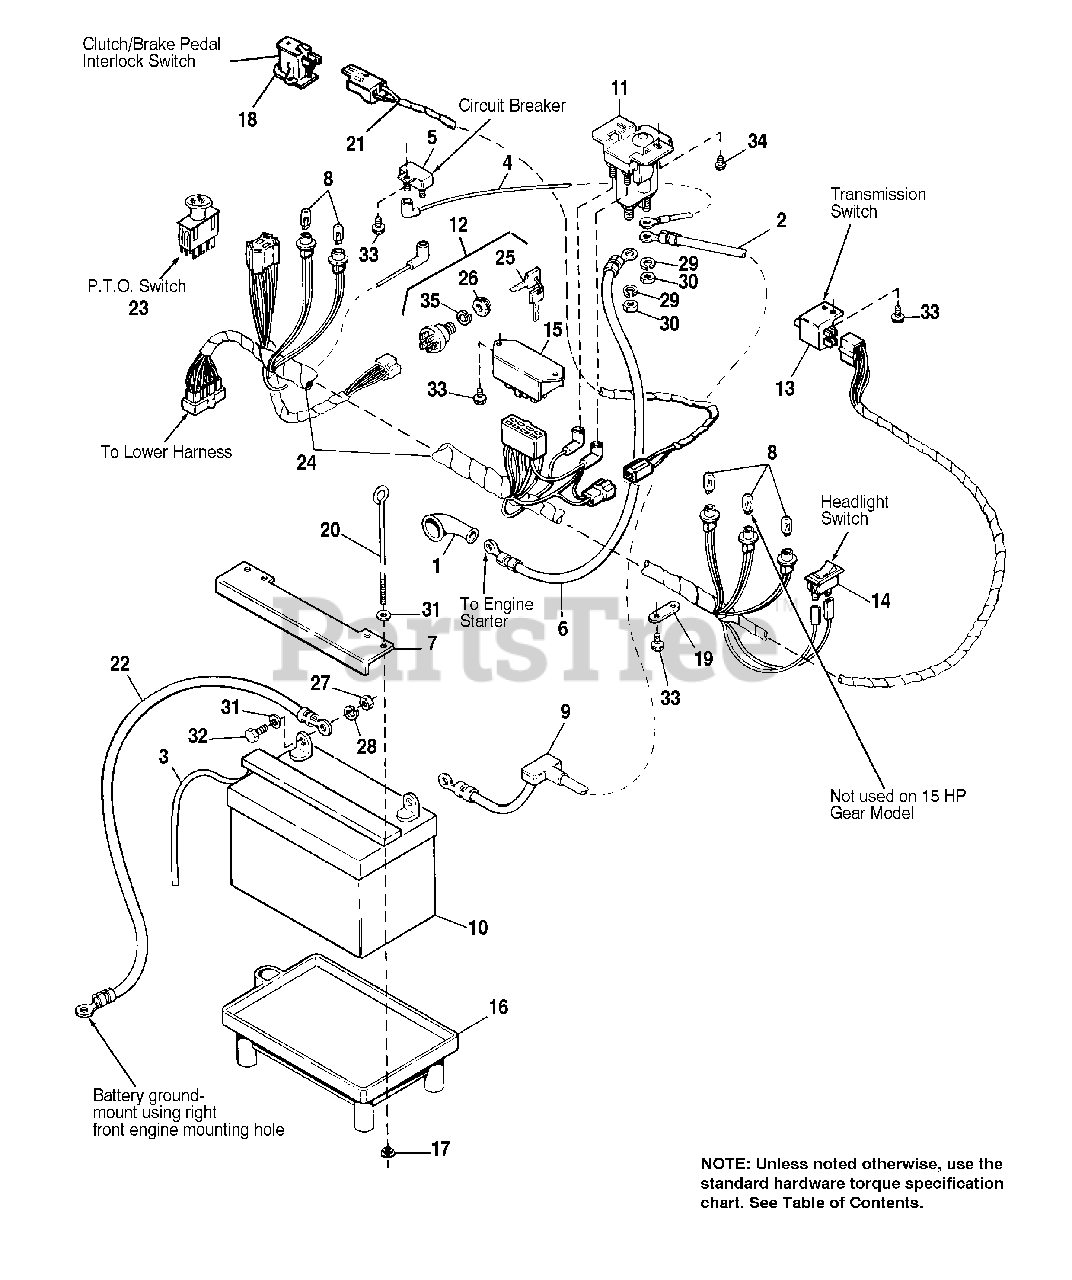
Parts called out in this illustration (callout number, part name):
1	COVER, Terminal
2	CABLE, Battery to Solenoid
3	HOSE, Battery, Drain
5	CIRCUIT BREAKER
6	CABLE, Solenoid to Starter
7	HOLD DOWN, Battery
8	BULB, Indicator Light
9	BOOT, Insulator
11	SOLENOID
12	IGNITION SWITCH ASSY.
13	SWITCH, Transmission, Neutral Start
14	SWITCH, Headlight
16	TRAY, Battery
17	NUT, Plastic, 1/4-20
18	SWITCH, Interlock, Clutch/Brake Pedal
19	STRAP, Wire Retainer
20	ROD, Battery Hold Down
22	CABLE, Battery to Ground
23	SWITCH, PTO Electric Clutch
24	HARNESS, Upper
25	KEY, Ignition
27	NUT, Hex, Full, 1/4-20
28	LOCKWASHER, 1/4
29	LOCKWASHER, 5/16
30	NUT, Hex, 5/16-24
31	WASHER, Plain, 9/32
32	CAPSCREW, Hex, 1/4-20 x 3/4
33	SCREW, Plastite, #8-16 x 1/2
34	SCREW, Plastite, 1/4-20 x 1/2
35	LOCKWASHER, Internal Tooth, 5/8
